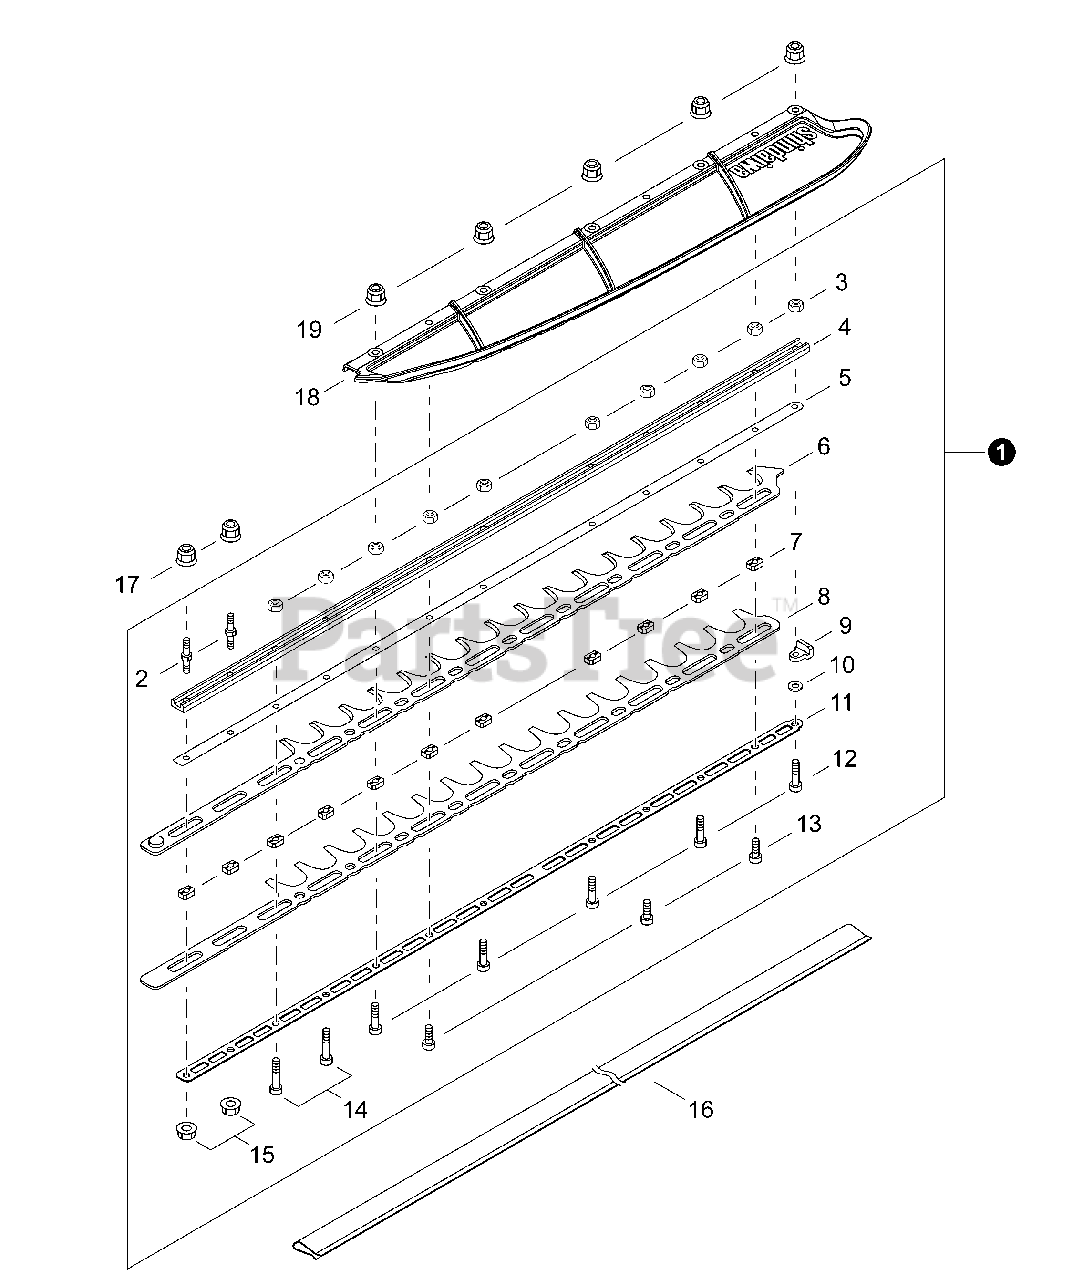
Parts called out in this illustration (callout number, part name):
1	CUTTER ASSY, 30"
2	STUD, MOUNTING M5
4	SUPPORT, CUTTER 30"
5	SUPPORT, CUTTER 30"
6	CUTTER 30"
8	CUTTER 30"
11	SUPPORT, CUTTER 30"
12	BOLT, TORX 5×25
13	BOLT, TORX 5×16
14	BOLT, TORX 5×30
16	SCABBARD
18	DEFLECTOR, DEBRIS
